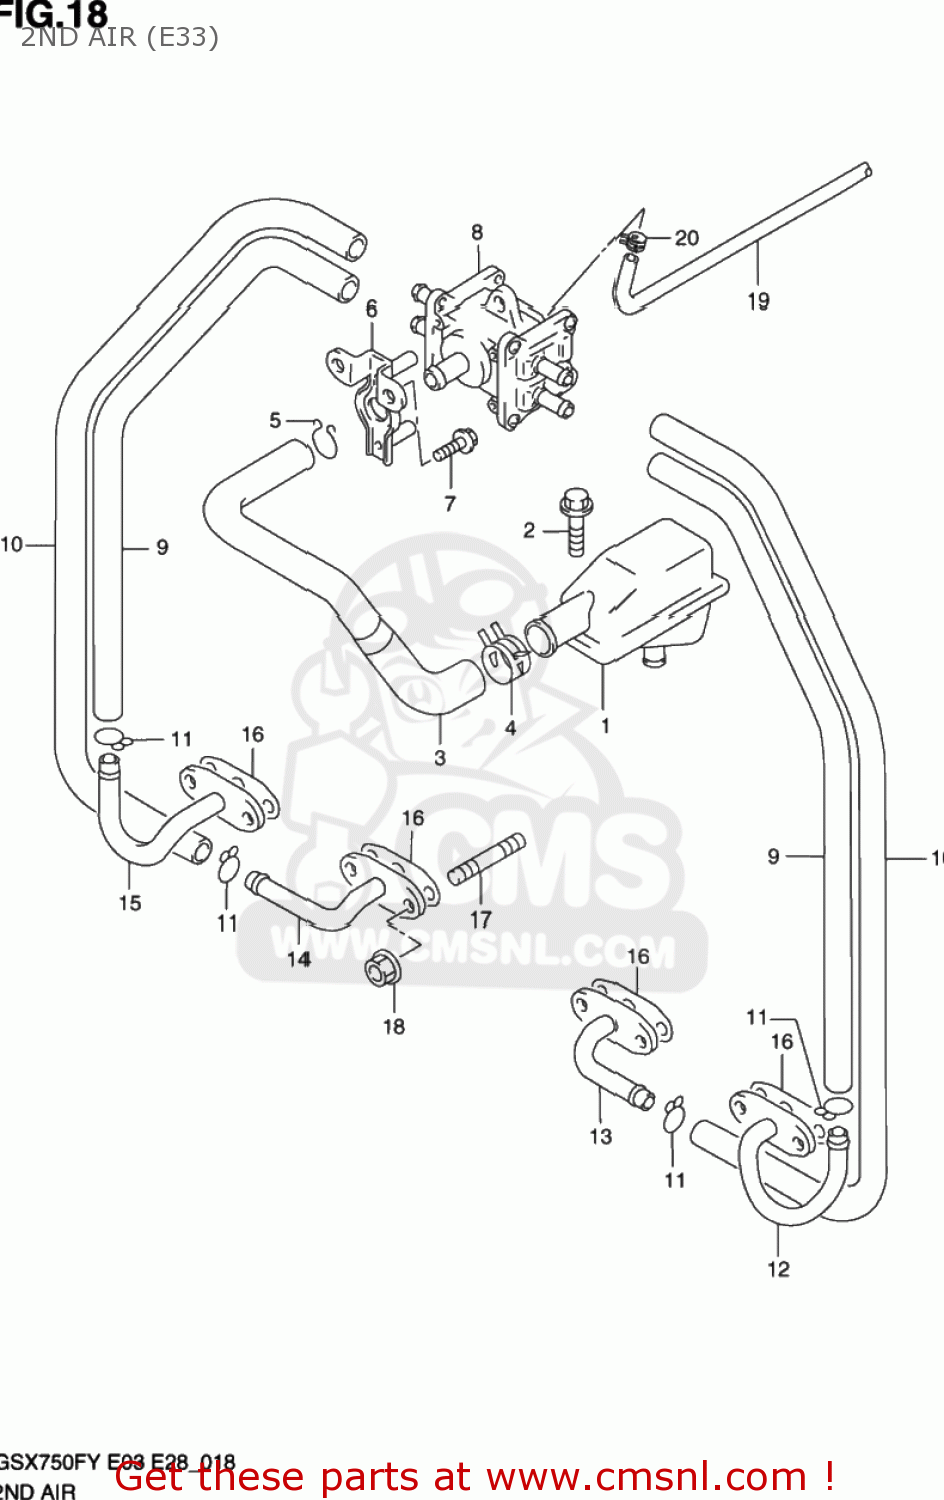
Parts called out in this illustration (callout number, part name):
1	CLEANER ASSY,2ND AIR
2	BOLT
3	HOSE,2ND AIR CLEANER
4	CLIP
5	CLIP
6	BRACKET,2ND AIR VALVE
7	BOLT
8	VALVE ASSY,2ND AIR
9	HOSE,2ND AIR VALVE OUTER
10	HOSE,2ND AIR VALVE INNER
11	CLIP
12	PIPE,2ND AIR NO.1
13	PIPE,2ND AIR NO.2
14	PIPE,2ND AIR NO.3
15	PIPE,2ND AIR NO.4
16	GASKET,2ND AIR PIPE (NAS)
17	STUD BOLT
18	NUT
19	HOSE(4.5X8.5X600)
20	CLIP
